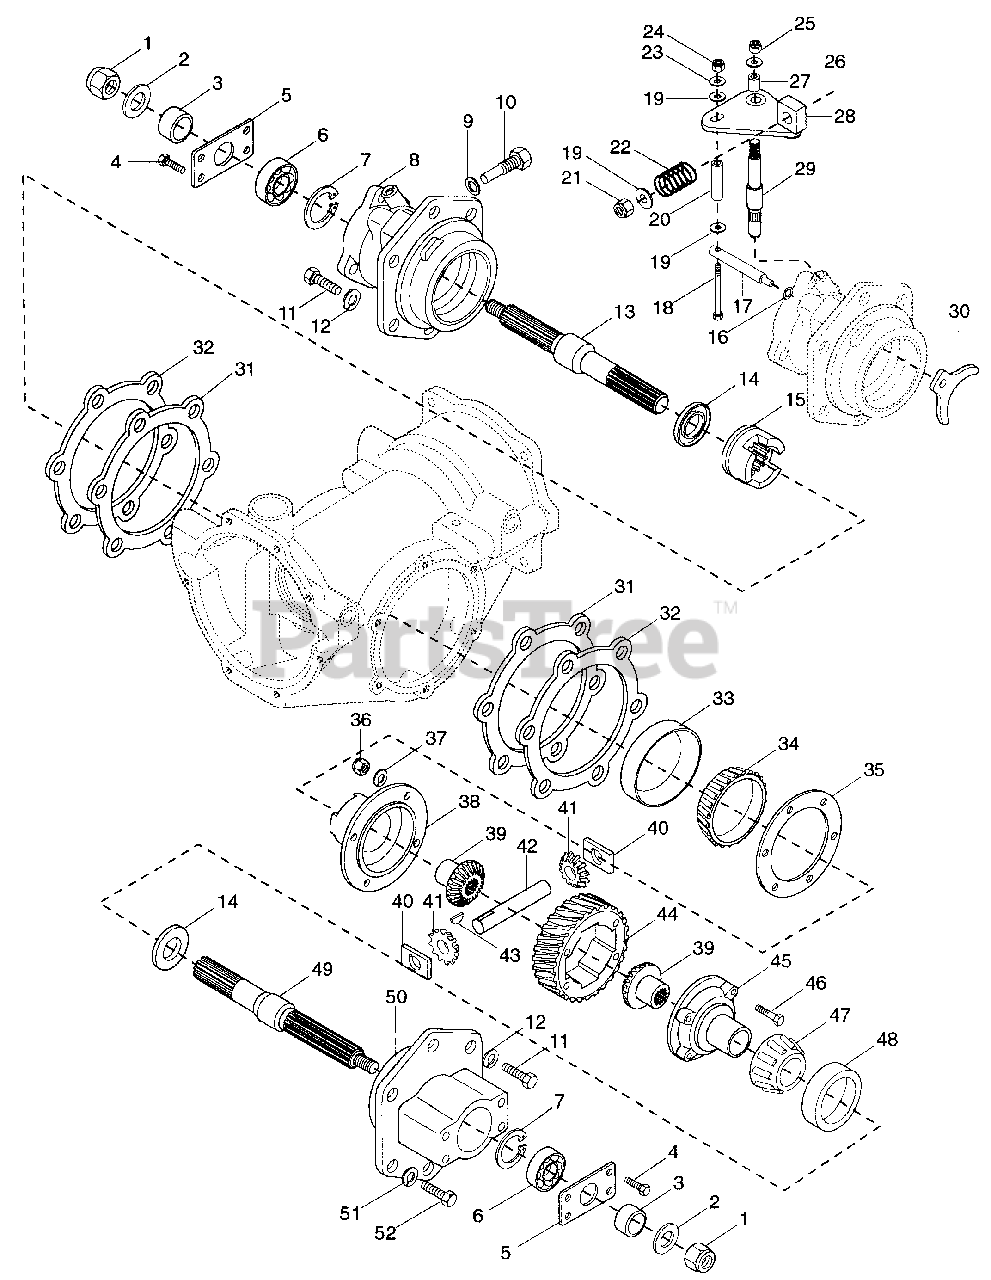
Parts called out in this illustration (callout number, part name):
1	Nut-Locking-Jam-Nylon .75-10
2	Washer-Flat .812 x 1.469 x .134
3	Bushing, Sleeve 1.02 x 1.37 x 1.37
4	Bolt-Hex .38-16 x .75 Grade 5
5	Plate, End
6	Bearing-Ball 1.0 x 2.0 x .56
7	Ring-Retaining-lnternal 2.210 x .062
8	Housing,Axle 2 Speed
9	Washer-Nut .63 x .875 x .062
10	Bolt-Hex .62-18 x .493 x 1.25
11	Bolt-Hex .50-13 x 1 Grade 5
12	Washer-Lock .50
13	Axle, Straight Differential Locking
14	Seal 1.188 x 2.000 x .250
15	Clutch, Sliding Differential Locking
16	O-Ring .437 x .625 x .093
17	Pin, Clutch Sliding
18	Bolt-Round Head Square Neck .25-20 x 2.25
19	Washer-Flat-Steel .406 x .812 x .065
20	Bushing, Sleeve .277 x .375 x 1.37
21	Nut-Locking-Nylon .375-16
22	Spring-Compression .067 x .72 x 2.0
23	Washer-Flat-Steel .281 x .62 x .065
24	Nut-Locking-Nylon .250-20
25	Nut-Locking-Nylon .312-18
26	Washer-Flat-Steel .344 x .688 x .065
27	Bushing-Sleeve .377 x .503 x .88
28	Weldment, Arm Shifter
29	Pivot, Stationary
30	Yoke, Shifting
31	Gasket, Axle Housing
32	Shim, Axle Housing .005
33	Bearing-Race 4.34 x .741
34	Bearing-Cone 2.69 x .87
35	Shim, .005 Clutch Worm Gear
36	Nut-Hex .312-24
37	Washer-Lock-lnternal .313 x .030
38	Housing, Differential Locking
39	Gear, Differential Bevel
40	Block, Drive
41	Gear, Spider Bevel
42	Pin, Spider Pinion
43	Key, Woodruff .13 x .38
44	Gear, 4-Lead Worm
45	Housing, Differential
46	Bolt-Hex .31-24 x 2.75
47	Cone, Roller Bearing; 50 MM x 21.5 MM
48	Cup, Roller Bearing; 82 MM x 17 MM
49	Axle, Straight
50	Housing, Axle
51	Seal-Oil Drain .563 x 1.250 x .091
52	Bolt-Hex .50-13 x 1.312 Grade 5
